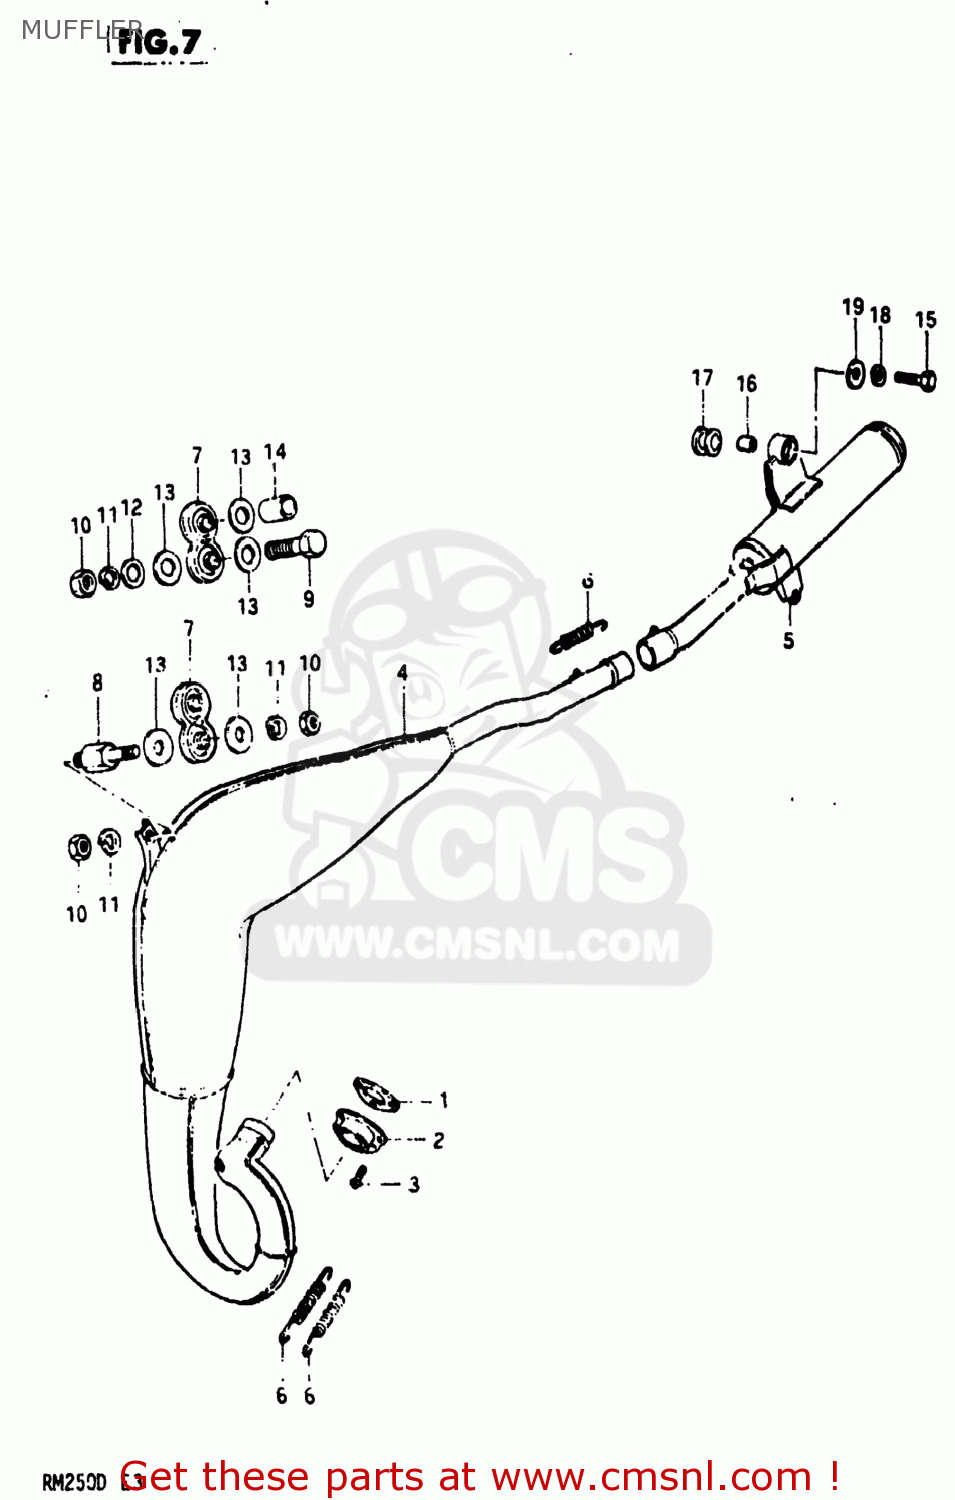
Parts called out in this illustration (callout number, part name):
1	GASKET,EXHAUST PIPE (MCA)
2	FLANGE,EXHAUST PIPE
3	SCREW
4	BODY,MUFFLER
5	BODY,MUFFLER
6	SPRING
7	DAMPER,MUFFLER
8	STUD
9	BOLT
10	NUT 8MM
11	LOCK WASHER
12	WASHER
13	WASHER
14	SPACER (8.6X16X23.5)
15	BOLT(8X32)
16	SPACER (8.6X12X17.5)
17	CUSHION
18	LOCK WASHER
19	WASHER (8.5X29X1.6)
